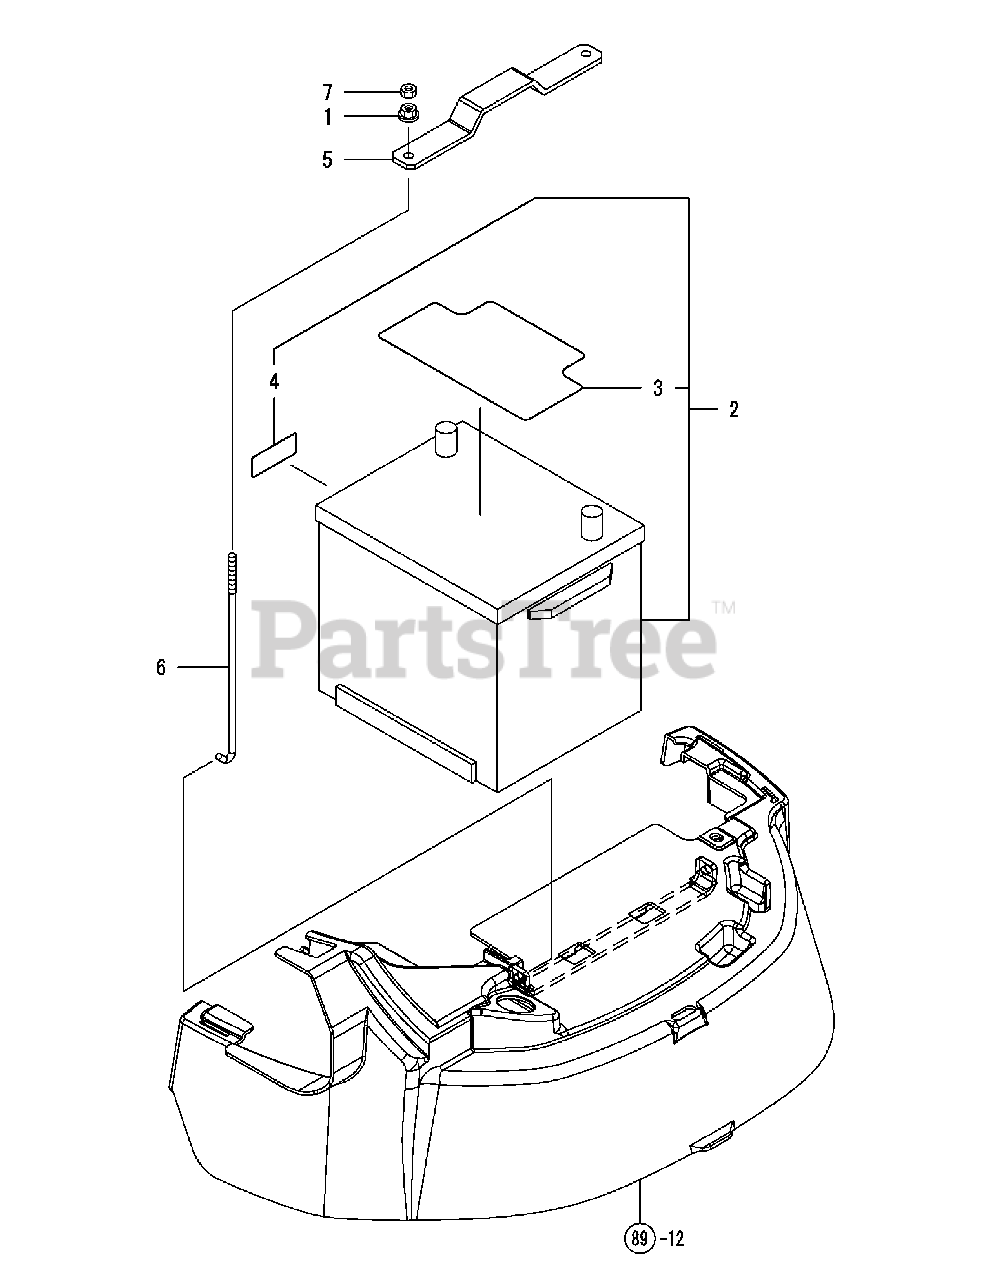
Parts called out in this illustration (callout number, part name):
1	NUT W/WASHER 6
2	BATTERY, 26R, ASSY
3	LABEL, BATTERY
4	LABEL, CA 65 WARN
5	CLAMP, BATTERY
6	ROD, BATTERY CLAMP
